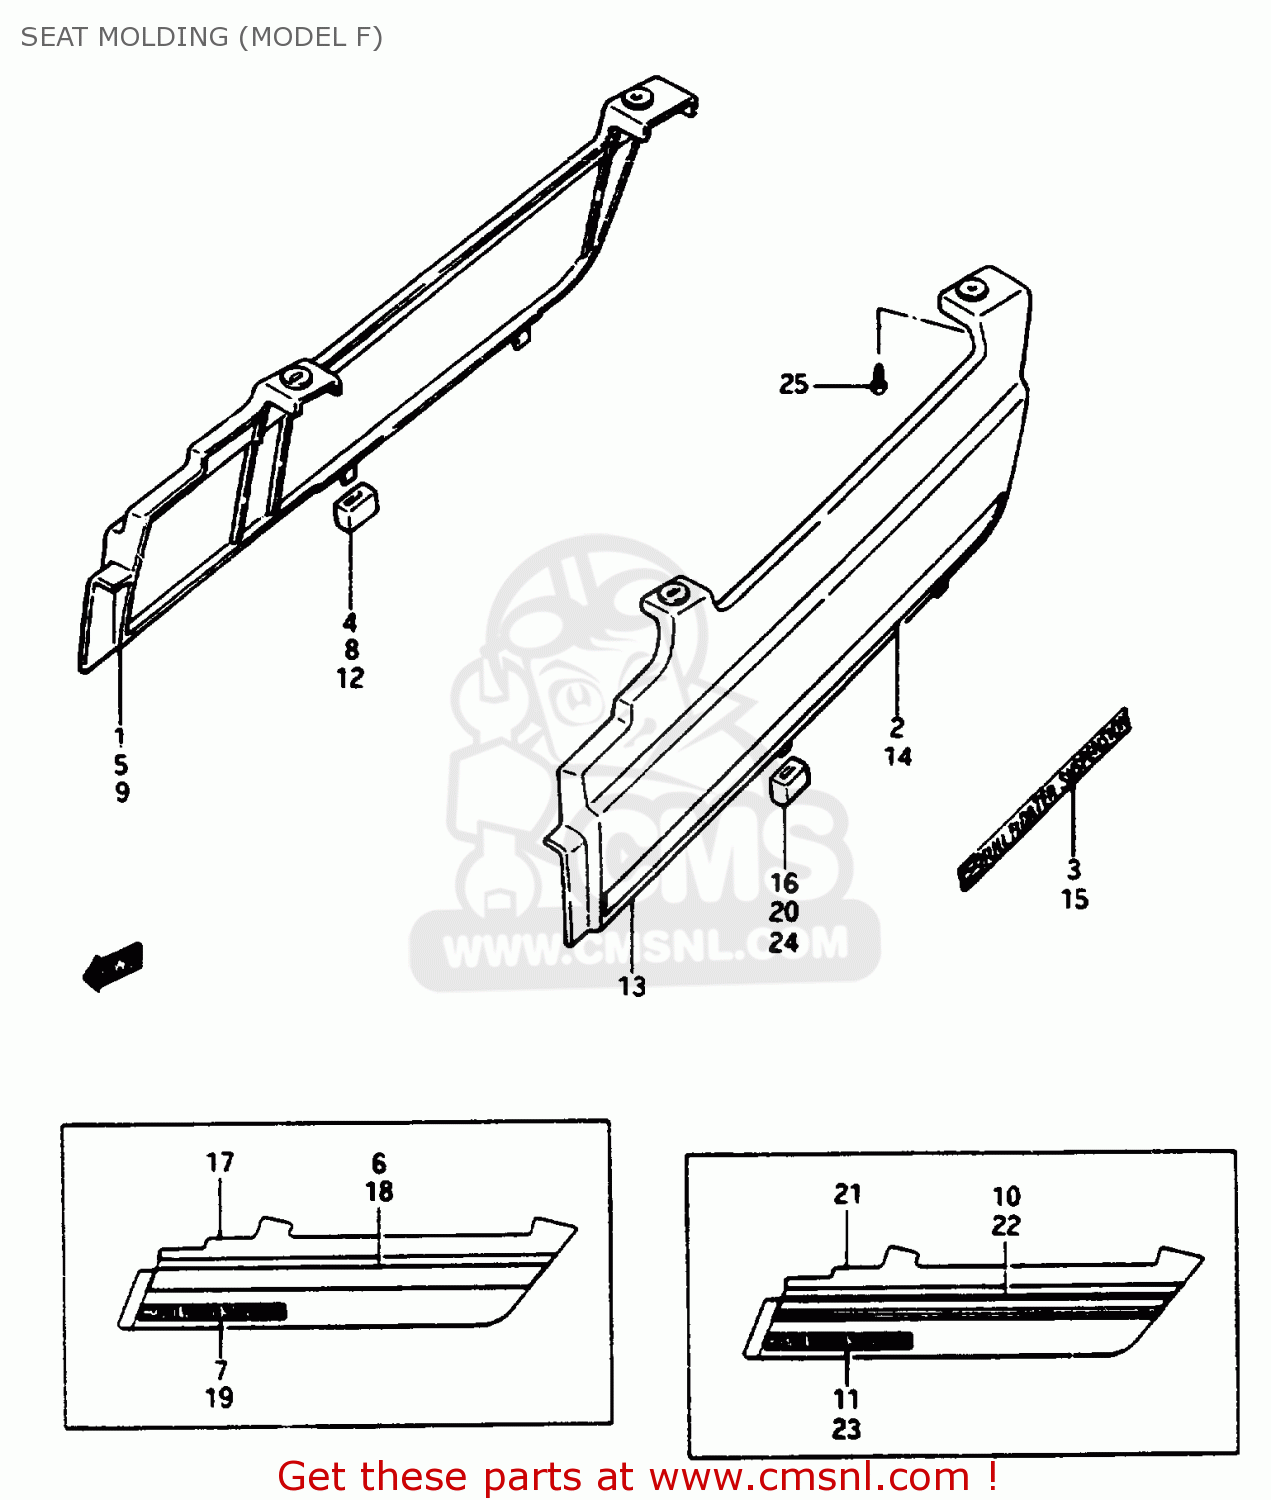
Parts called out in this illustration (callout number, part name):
1	MOLDING,SEAT,RIGHT
2	TAPE SET,SEAT MOULDING
3	EMBLEM
4	CAP,SEAT,MOLDING
5	MOLDING, SEAT RH
6	TAPE SET,SEAT MOULDING
7	EMBLEM
8	CAP,SEAT,MOLDING
9	MOLDING,SEAT,RIGHT
10	TAPE SET,SEAT MOULDING
11	EMBLEM
12	CAP,SEAT,MOLDING
13	MOLDING,SEAT,LEFT
14	TAPE SET
15	EMBLEM
16	CAP,SEAT,MOLDING
17	MOLDING, SET LH
18	TAPE SET,SEAT MOULDING
19	EMBLEM
20	CAP,SEAT,MOLDING
21	MOLDING,SEAT,LEFT
22	TAPE SET
23	EMBLEM
24	CAP,SEAT,MOLDING
25	SCREW
